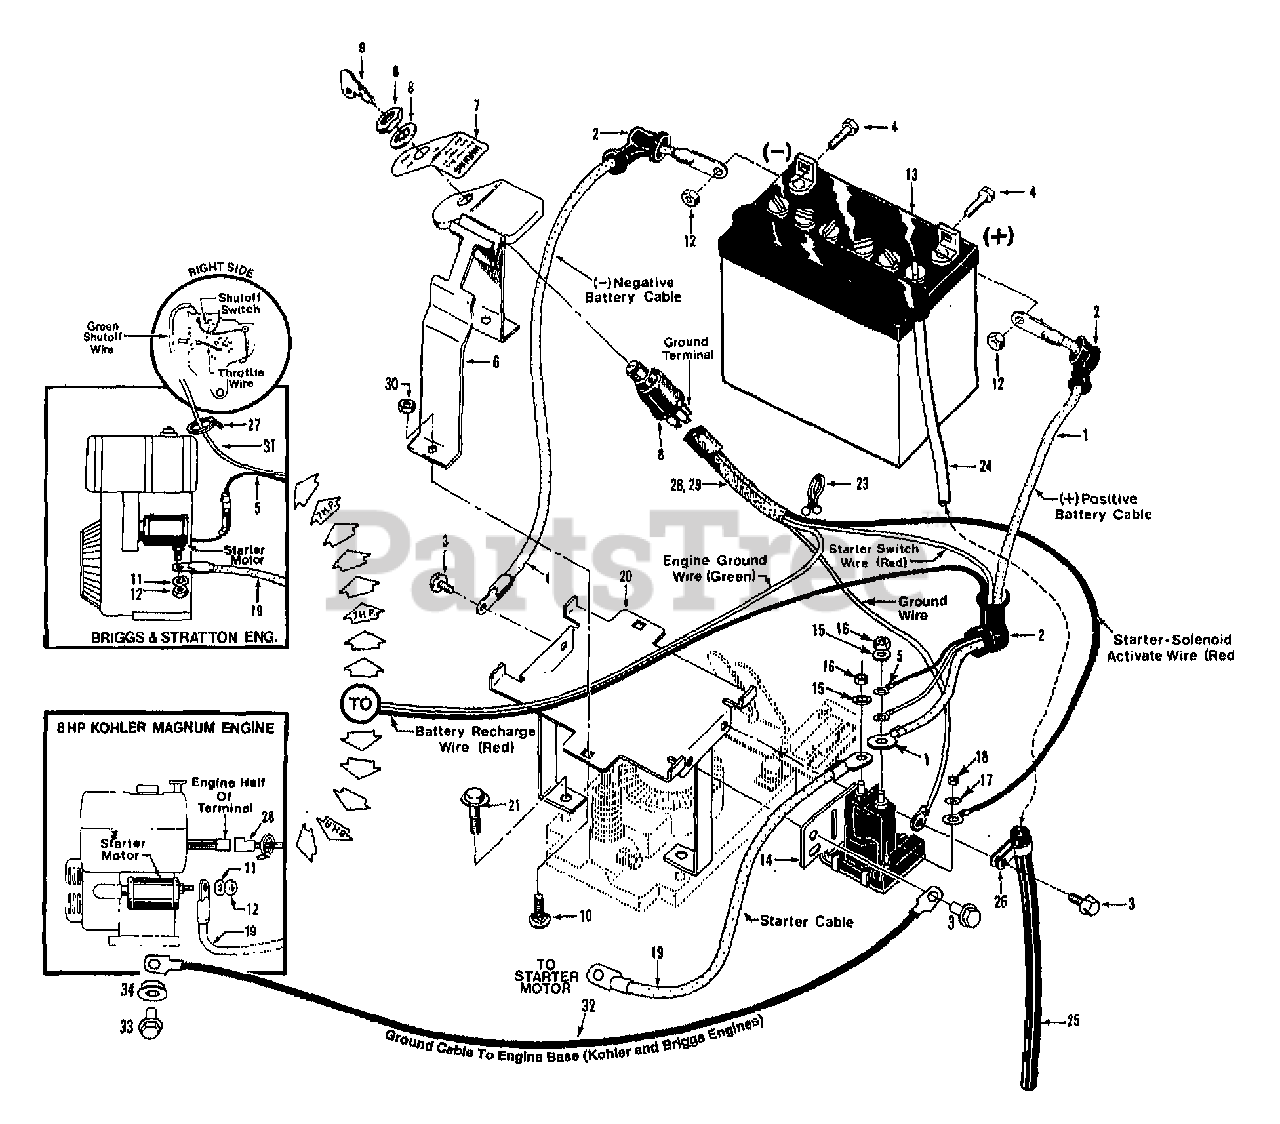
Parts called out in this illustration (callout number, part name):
1	CABLE-BATTERY 10"
2	BOOT-BATTERY CABLE
3	SCR-HWH 1/4-20 X .5 STH
4	SCR-HH 1/4-20X.625
5	WIRE-RECHARGE 5&7 BRIGGS
6	KEYSWITCH W/DECAL HORSE
7	DECAL-IGNITION TILLERS
8	ASSM-KEYSWITCH ELEC TLR
9	KEYS-IGN T/BLAZER 1 PAIR
10	SCR-CARR 1/4-20X1.25
11	WASHER-LK .25 ZP
12	NUT-HEX 1/4-20 ZP
13	BATTERY-12 VOLT HORSE
14	SOLENOID
15	WASHER-LK .312 ZP
16	NUT-HEX 5/16-24
17	WASHER-EXTERNAL TOOTH 1
18	NUT-HH M10-32X.125
19	CABLE-BATTERY 12"
20	BRKT-BATTERY OPC PNT
21	SCR-HFLK 3/8-16X1.50
22	THIS REF. NO. NOT USED
23	TIE-TWIST LOCK
24	TUBE-VENT BATTERY/HSE
25	TUBING-RUBBER
26	CLAMP
27	TIE-RED
28	KIT-WIRE HARNESS ASSM
29	ASSM-WIRE HARNESS
30	NUT-HF/LK 1/4-20 ZP
31	ASSM-WIRE SWITCH/GROUND
31	CABLE-BATTERY 15"
32	CABLE-BATTERY 15"
33	SCR-HFLK 5/16-18X1.00 ZP
34	NUT-HFLK 5/16-18 ZP
